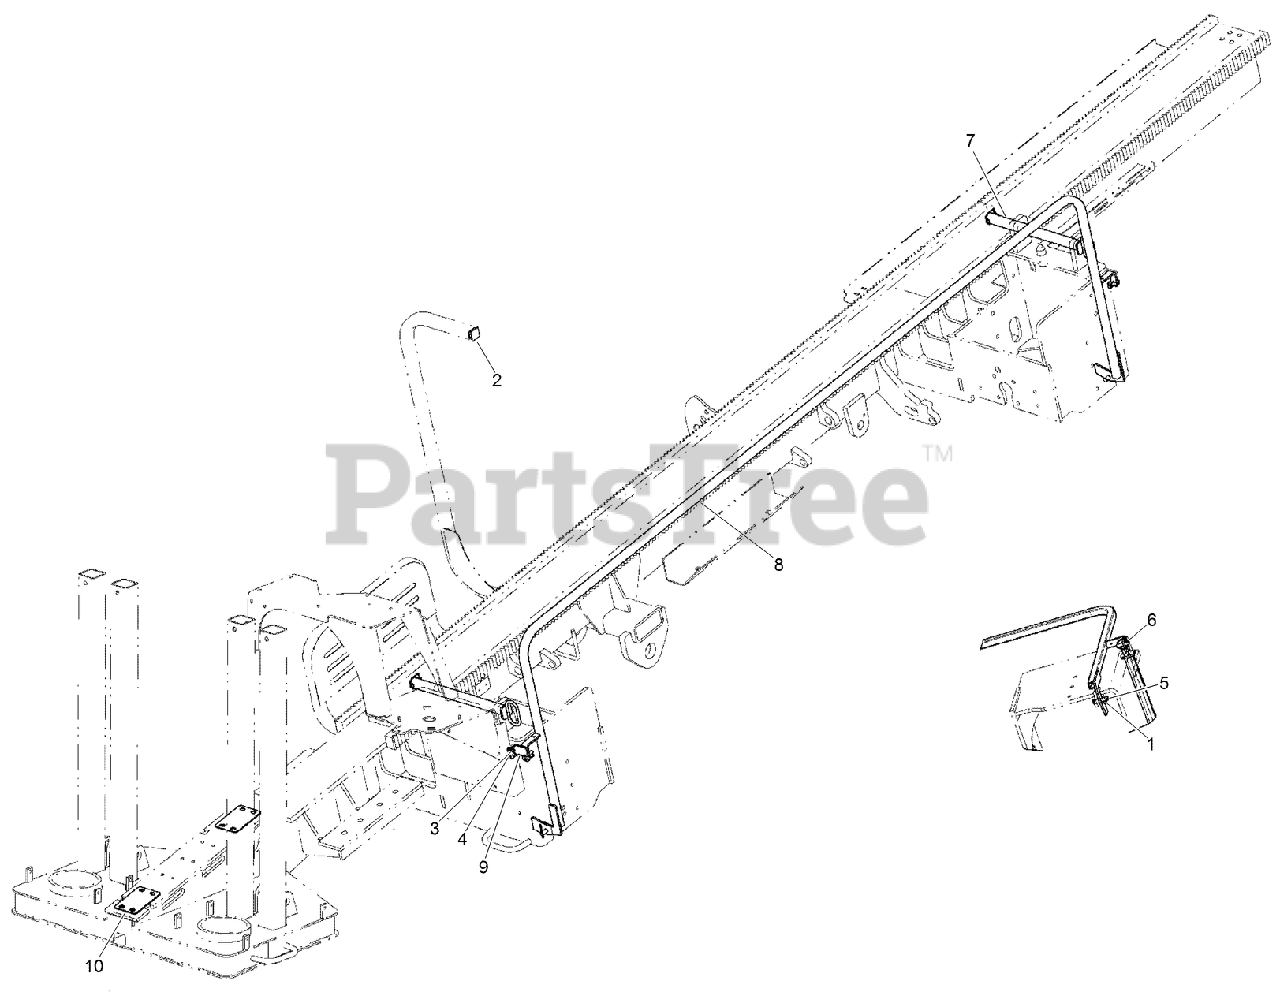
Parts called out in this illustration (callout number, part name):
1	PIN-cotter, 5/32 x 1-3/4 inch
2	CAP-SQUARE, PLASTIC
3	NUT, METRIC FLANGE PREVAILING - M6 Zinc
4	SCREW, METRIC FLANGE w/BODY-M6 x 25
5	PIN-CLEVIS
6	PIN-SNAP RING
7	ASSEMBLY - Rod Box Pin
8	ASSEMBLY - Guard
9	BRACKET-ANGLE, GUARD
10	PLATE-SHIM, BUSHING GUIDE
